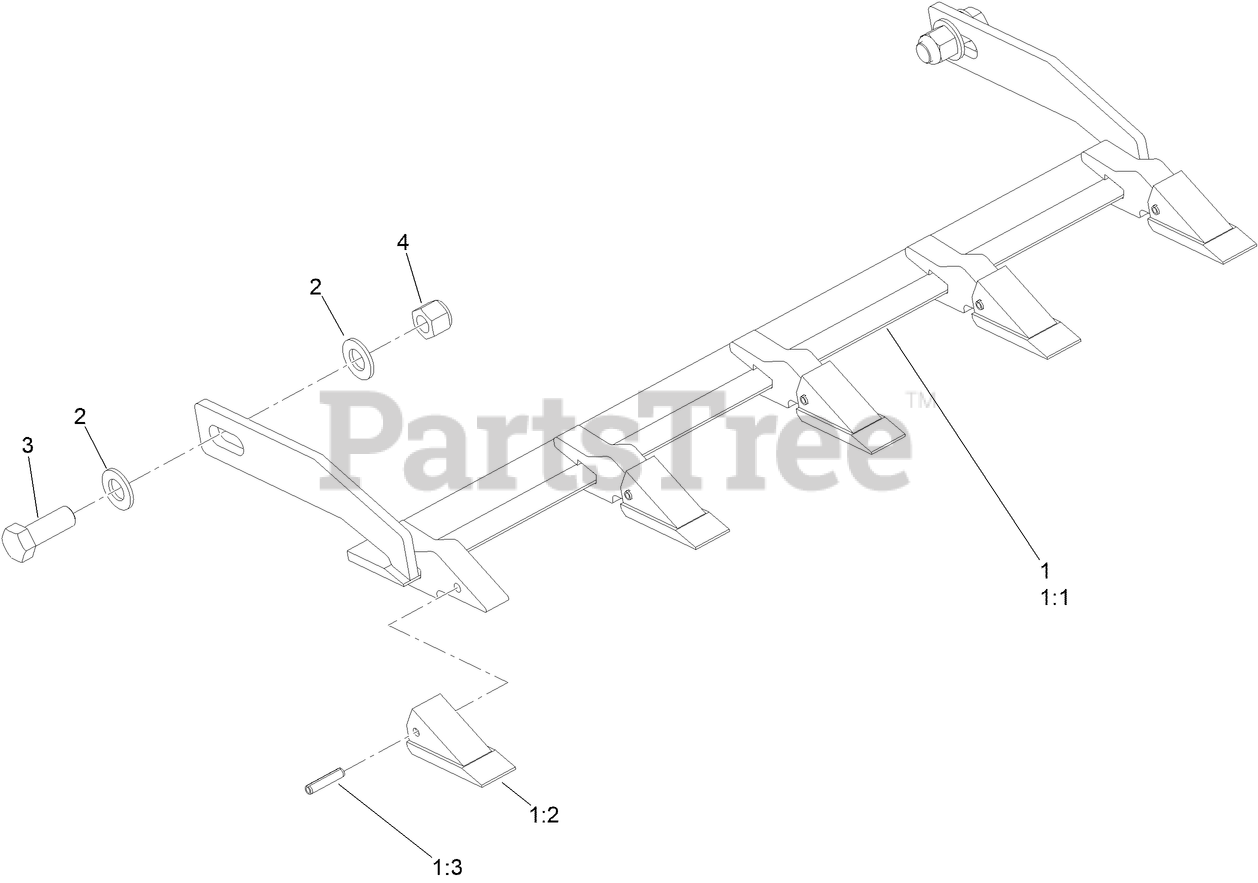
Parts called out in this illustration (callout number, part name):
1	NARROW TOOTH BAR ASM
1:1	NARROW TOOTH BAR ASM WELDED
1:2	TOOTH-BUCKET
1:3	PIN-ROLL
2	WASHER-FLAT
3	SCREW-HH
4	NUT-LOCK, NI
